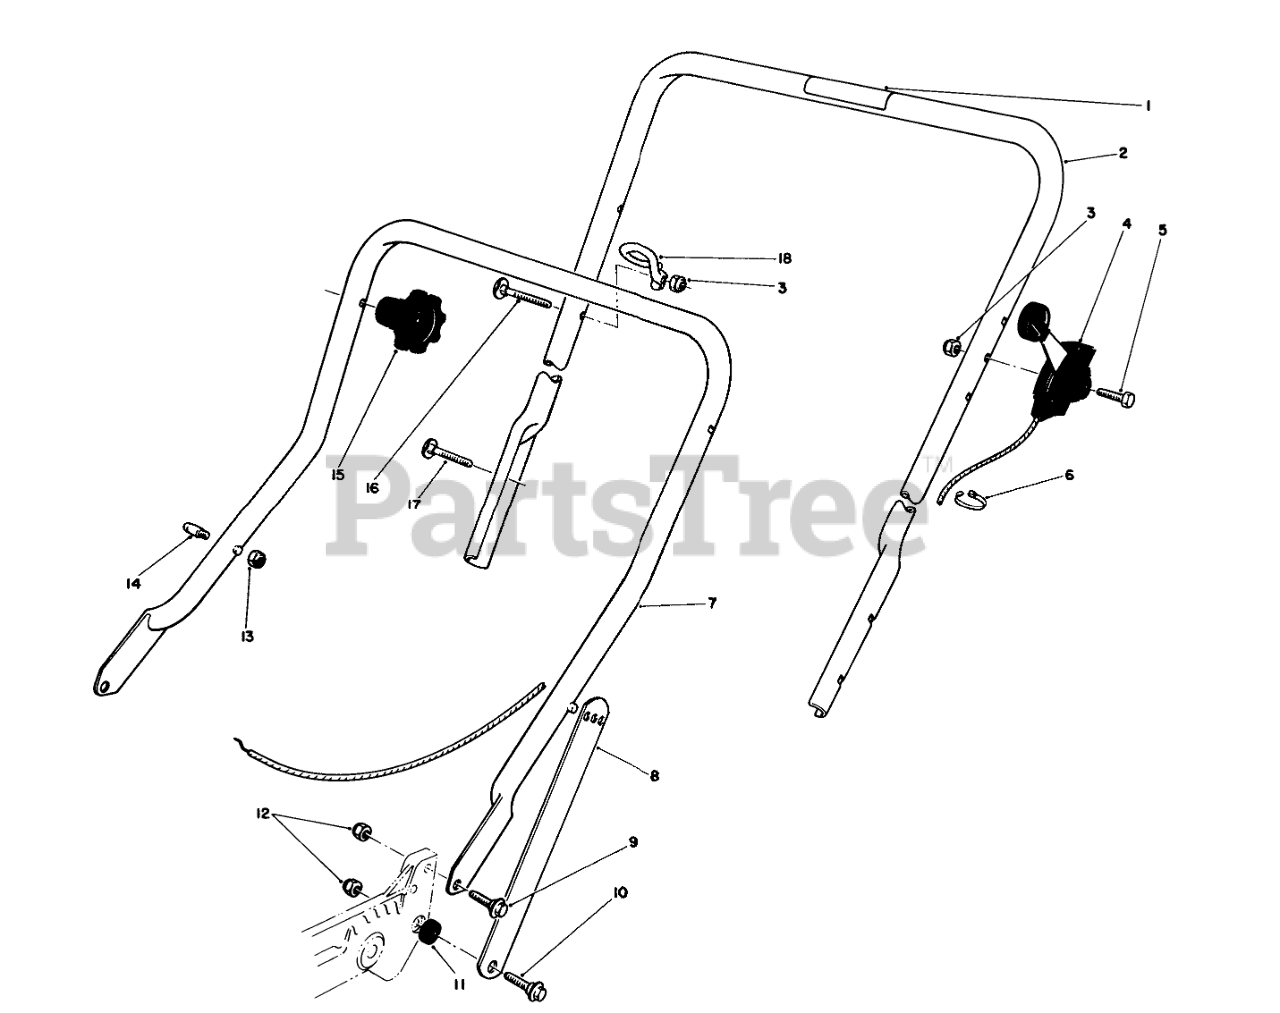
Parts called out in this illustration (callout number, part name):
1	Decal-Danger
2	Handle-Upper (Incl. Ref. #1)
3	NUT-LOCK, NI
4	THROTTLE CONTROL - R&S
5	SCREW-HANDLE
6	TIE-CABLE
7	LOWER HANDLE ASM
8	Handle Latch
9	SCREW-SHOULDER
10	SCREW-SHOULDER
11	SPACER
12	NUT-LOCK, NI
13	NUT-LOCK, NI
14	HANDLE PIN
16	HANDLE SCREW
17	5/16-18 X 2 HNDLE SCREW
18	Guide
